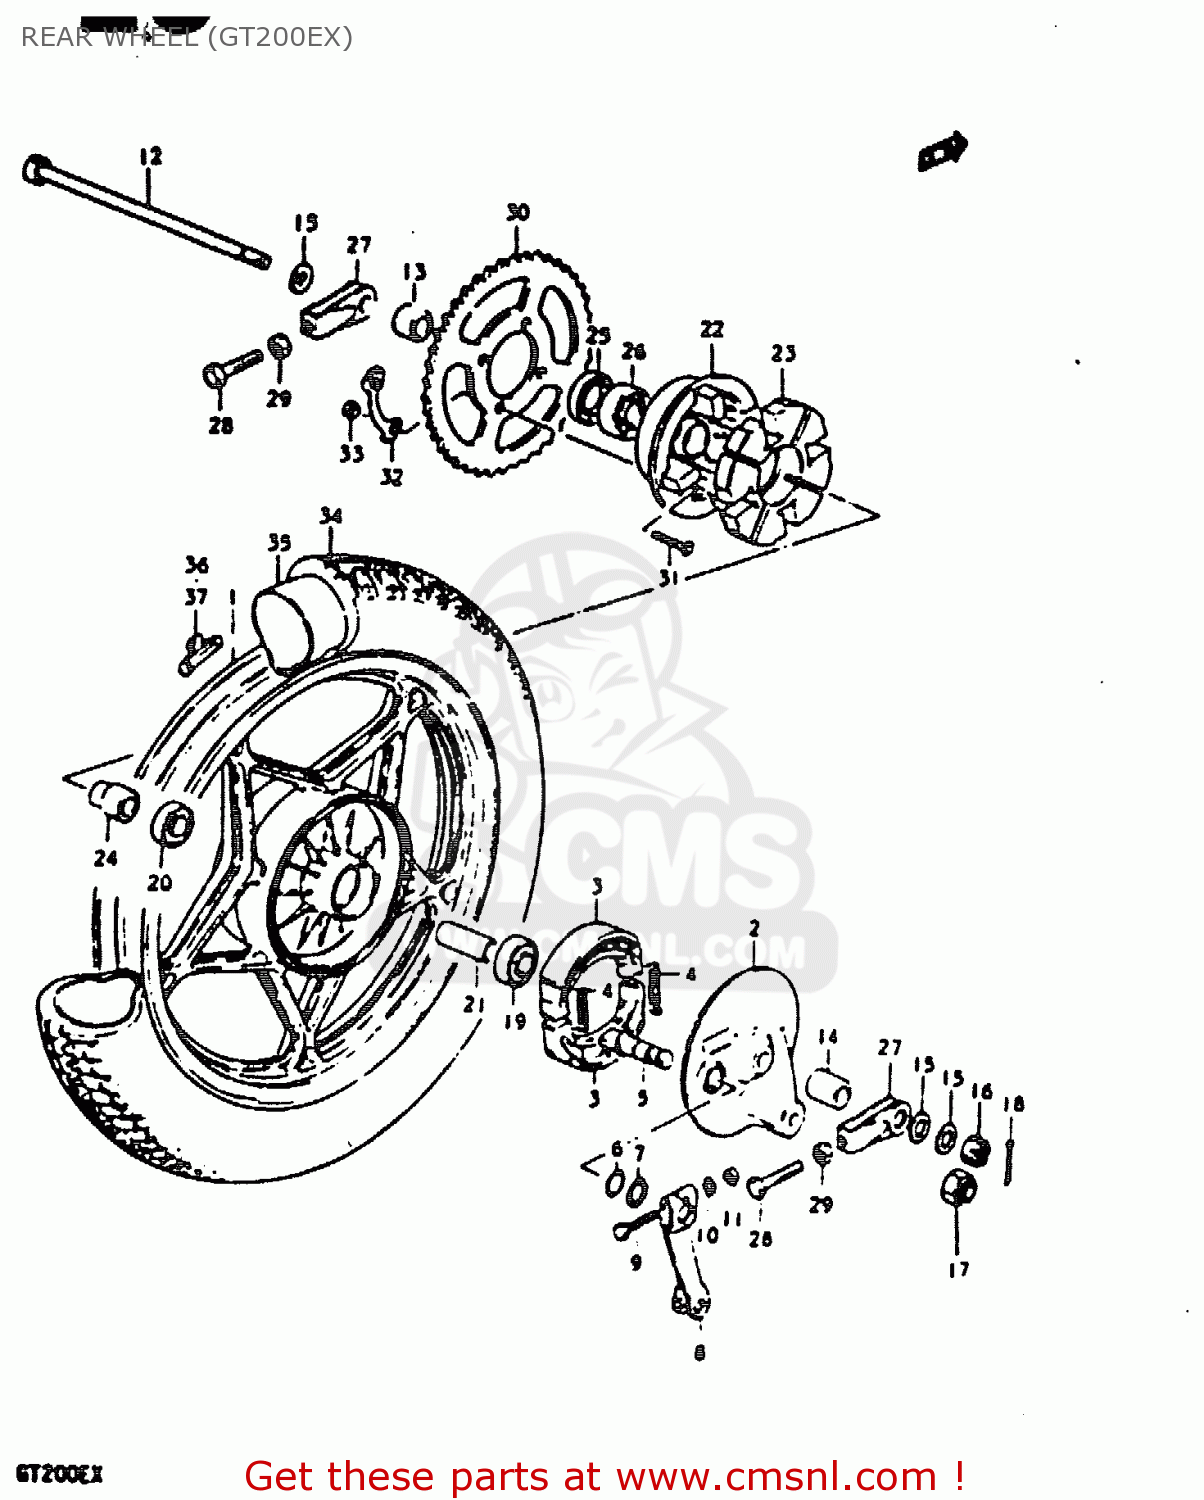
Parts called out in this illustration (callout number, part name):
1	WHEEL, REAR (18*1.60)
2	PANEL, REAR WHEEL
3	SHOE,BRAKE
4	SPRING(L:34)
5	CAM,FRONT BRAKE
6	O-RING (D:2.4 ID:13.8)
7	WASHER (14.5X22X1.6)
8	LEVER,RR BRAKE CAM
9	BOLT(6X33)
10	WASHER
11	NUT
12	AXLE,REAR
13	SPACER(15X28X19)
14	SPACER(15.2X26X33)
15	WASHER
16	NUT
18	COTTER PIN
19	BEARING
20	BEARING
21	SPACER(15.3X21.7X63)
22	DRUM,RR SPROCKET
23	ABSORBER ASSY,HUB SHOCK
24	RETAINER,RR SPROCKET MTG
25	SEAL,OIL(28X47X7)
26	Bearing
27	ADJUSTER,CHAIN
28	BOLT
29	NUT
30	SPROCKET,RR
31	BOLT(8X33.5)
32	WASHER
33	NUT
34	TIRE
35	TUBE,INNER
36	BALANCER,WHEEL
37	BALANCER,WHEEL
